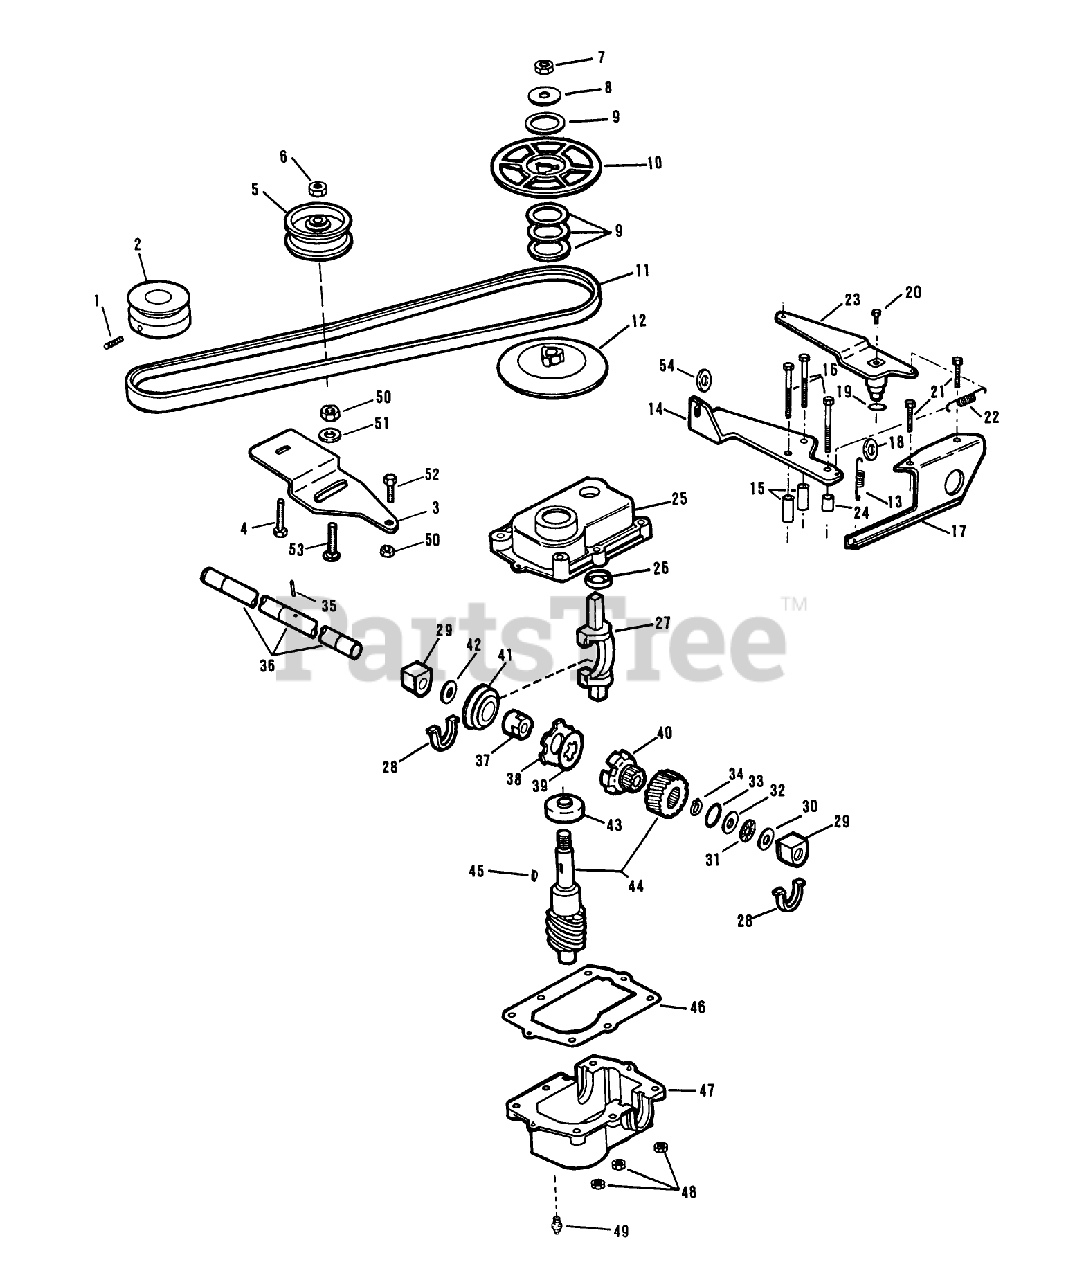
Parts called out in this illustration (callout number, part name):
1	SET SCREW F
2	PULLEY ENG F
5	PULLEY IDLER NHI
6	NUT-JAM, LOCKING
7	LOCKNUT
8	WASHER
10	PULLEY UPPER PL
11	V-BELT F
12	PULLEY LOWER PL
13	SPRING EXTEN D&B
14	CONDUIT ANCHOR BRKT
18	WASHER
19	O-RING
20	SCREW SEMS SM
22	SPRING
26	GUIDE ELCO
27	FORK SHIFT
29	BEARING & SEAL AY (12)
30	THRUST WASHER
32	WASHER-THRUST
34	RET RING
35	PIN DRIVE LOCK
38	ORD 684683,
39	ORD KIT 684683
40	DRIVER BROCKWAY
42	WASHER
43	BEARING-BALL
45	KEY GALGER
46	GASKET HOOSIER
48	LOCKNUT E
50	NUT-LOCK F
